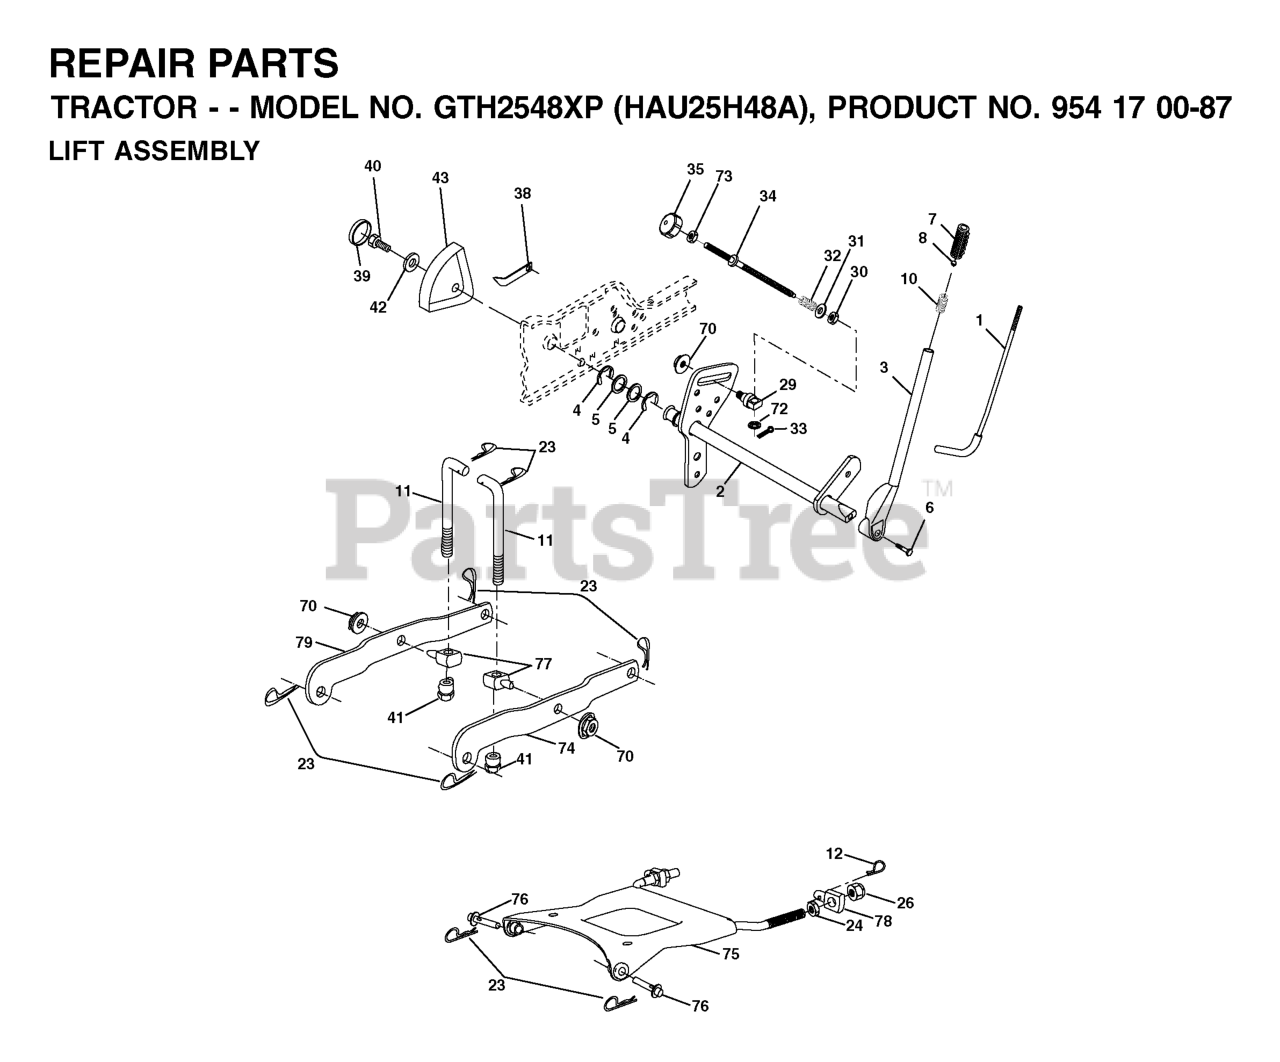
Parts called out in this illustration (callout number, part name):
1	DECK SVC 54"
6	COVER.MANDREL.LH.54"20
7	COVER.MANDREL.RH.54.20
11	BLADE.BAGGING.54"
12	ROD.ANTI.SWAY.48/54"K4
13	SHAFT ASSY, MANDREL SHAFT
14	RP.HOUSING.MANDREL.4PT.
15	BEARING.MANDREL.TOP.EXTENDED
16	WASHER
18	BOLT
19	PIN.COTTER.5/16.BOW TI
21	LOCKNUT
24	CAP-SLEEVE LT
25	SPRING, TORSION
26	NUT PUSH M
27	DEFLECTOR
29	ROD.HINGE
32	PULLEY/MANDREL
33	NUT.FLANGE.LOCK.TOP
35	SCREW.SEMS.7/16-20X1.HEX.HEAD
39	RB PULLEY.IDLER.4.50/HUB SPEC
41	BOLT.HEX.WASHR.HED.313-18X1.19
46	SCREW.1/4-20X5/8
47	BELT.DECK.DRIVE.BELT.54
49	NUT LOCK FLG 3/8-16 UNC
52	PULLEY.IDLER.2006
58	BAFFLE.RIGHT.54"
59	BAFFLE.LEFT.54"
60	BAFFLE CENTER 54" MOWER
61	PLATE.REIN.FRONT.BOLT54"X431
62	PLATE.REIN.SIDE.BOLT.54"X431
63	BOLT.CARRIAGE.5/16-18
98	SPRING, DECK DRIVE
113	RHSSNB 5/16C X 1.0
114	ROD TENSION RELIEF
116	BOLT.SHOULDER.3/8-16X3-5/8.
117	WHEEL.GAUGE.RALLY
120	WASHER
122	BUSHING.RELIEF.TENSION
184	NUT LOCK HEX FLANGE 5/16-18
185	NUT.LOCK.FLANGE.7/16
187	STUD.FASTNER.W/ANTI-ROTATE
189	ARM.SUSPENSION.MOWER
190	BOLT.SHOULDER
192	KEEPER.BELT.IDLER.54"T
194	BOLT.HEX.WASHER.HEAD.7/16-24X
196	CARRIAGE BOLT 3/8-16 X
241	SCREW.TT.#10-32X.5.3/8.FLANGE
242	PORT.WASHOUT
245	WASHER
